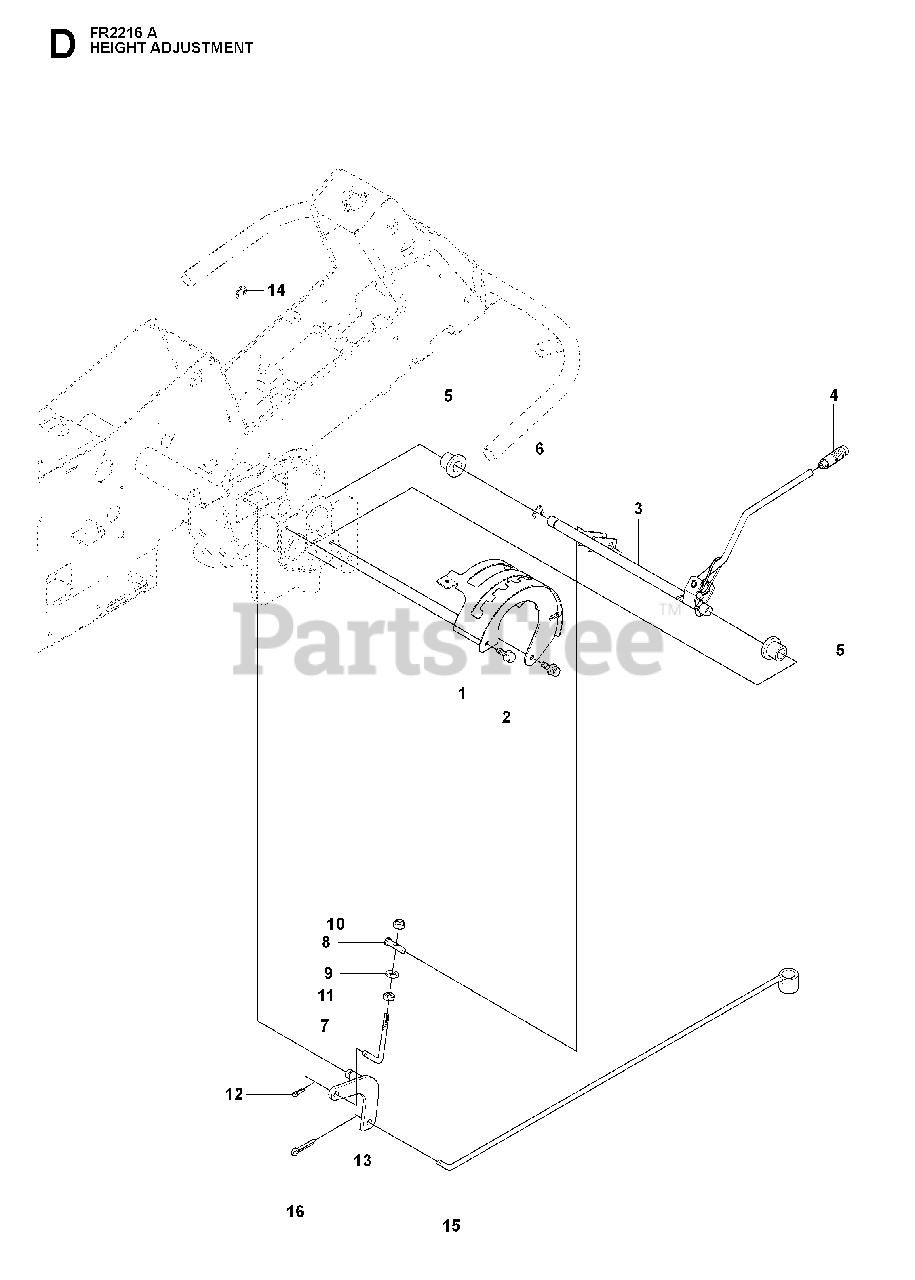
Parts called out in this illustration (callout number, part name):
4	GEAR STICK KNOB
5	BUSHING
9	WASHER
10	LOCKNUT M8
11	NUT
12	SPLIT PIN
14	RETAINING RING
15	CLUTCH ROD
16	SPLIT PIN
